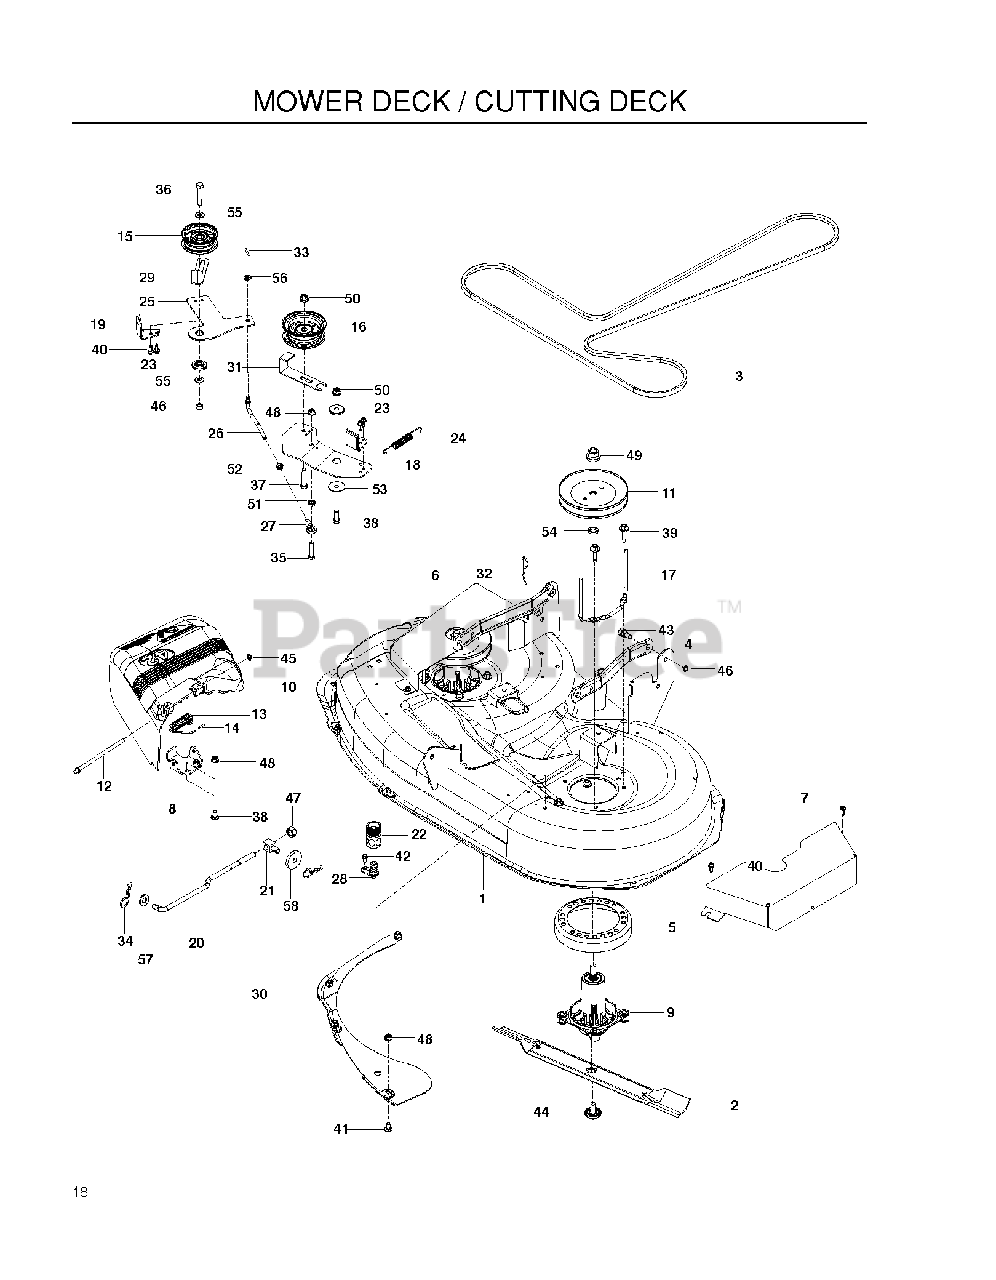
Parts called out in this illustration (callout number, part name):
1	DECK.SVC W/DECALS 42" HTC RZ
2	BLADE, 42" MULCHING STD
3	BELT, EL118
4	ARM.SUSPENSION.MOWER
5	STRIPPER-ROUND-UNIVERSAL
6	GUARD.RIGHT.BELT.42"BLACK
7	GUARD.LEFT.BELT.42" BLACK
8	BRKT.DEFLECTOR.38"2005+
9	RB MANDREL.ASM.SUB-NON.GR
10	DEFLECTOR 42
11	PULLEY.MANDREL.5.438.P
12	ROD, HINGE
13	SPRING, TORSION DEFLECTOR
14	CAP-SLEEVE
15	IDLER PULLEY
16	PULLEY.IDLER.FLAT
17	BELT KEEPER.MANDREL.38"COATED
18	ARM.IDLER.BLACK
19	ARM, LH BRAKE
20	LINK LIFT SUSP. FRONT MOWER
22	COUPLING.QUICK CONNECT
23	SPACER.RETAINER
24	SPRING RETURN
25	ARM.BRAKE.42.BLACK
26	LINKAGE, DECK BRAKE
27	BALL JOINT, RIGHT HANDED
28	PORT.WASHOUT
29	GUIDE, BELT
30	BAFFLE VORTEX 42
31	KEEPER, BELT
32	SPRING.RETAINER.YELLOW.ZINC
33	RP_COTTER PIN 1/8 X 3/4
34	HAIRPIN #4
35	CAPSCREW 5/16 X 1/1/2 HEX HEAD
36	HCS 3/8C X 2
37	HCS 3/8-16 X 1 3/4 GR5
38	HCS 3/8-16X1.GRD.5.ZD
39	WASHER HEAD SCREW
40	SCREW- 1/4-20 X 5/8
41	CARRIAGE BOLT 5/16C X 5/8"
42	SCREW 3/8C X 3/4 HEX CAP
43	SB 3/8-16 X 3/8 SKT HD ZD
44	BOLT.WASHER.ASM.7/16-2
45	NUT PUSH M
46	NUT HEX 3/8-16 NYLON, THIN
47	NUT, 7/16-20 HEX NYLOC ZC
48	5/16-18 NYLOC FLANGE NUT
49	LOCKNUT - 9/16
50	NUT 3/8-16 HEX FLG NYLOC ZD
51	NUT 5/16C WHIZ
52	NUT 5/16C HEX
53	WASHER, FRICTION
54	WASHER-SPACER
55	WASHER 3/8 SAE FLAT
56	FLAT WASHER 5/16 SAE
57	WASHER 1/2" FLAT
58	SPINDLE WASHER
